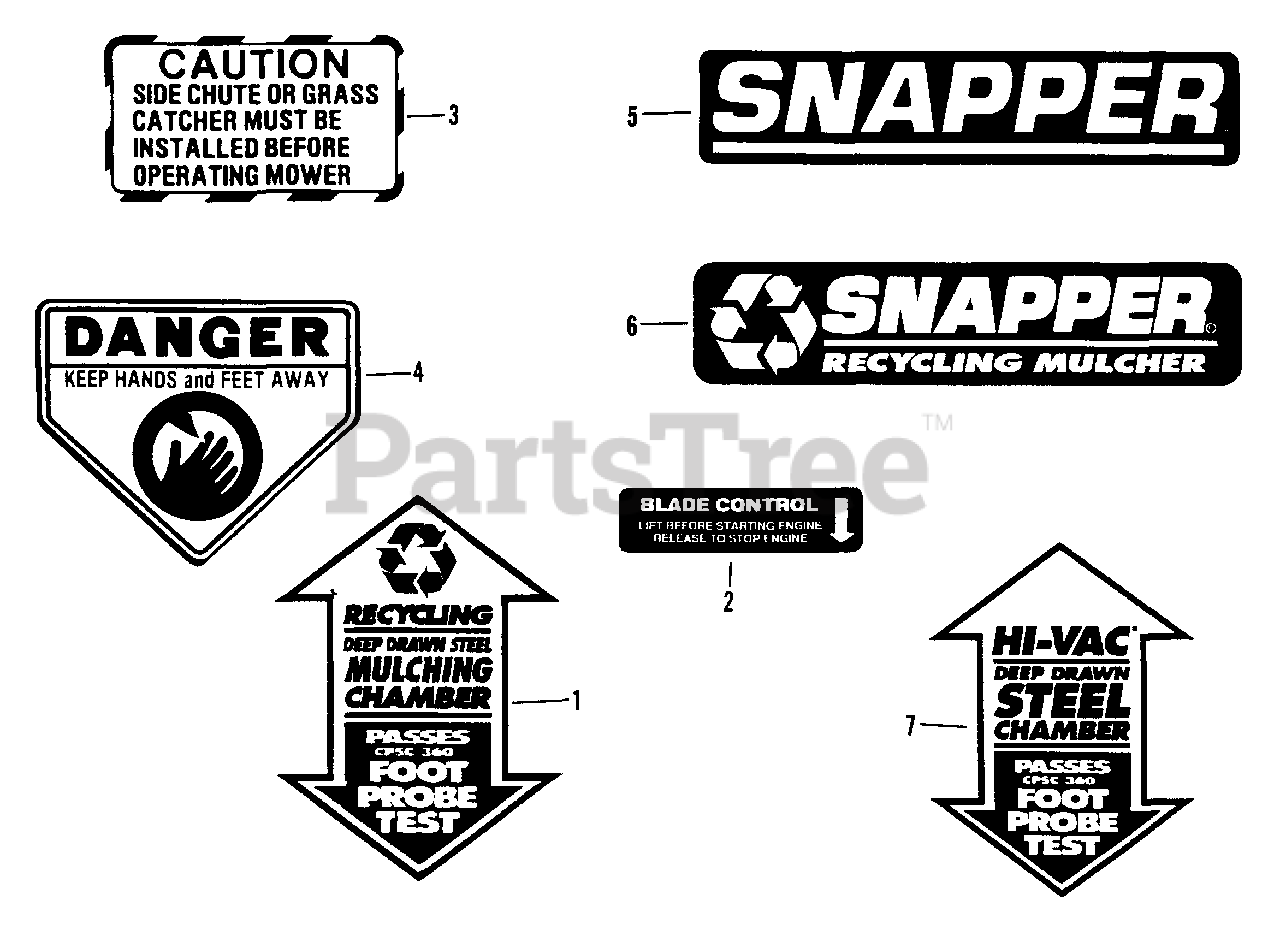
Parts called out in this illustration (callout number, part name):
1	DECAL, Mulching Chamber/Foot Probe
2	DECAL, Blade Control
3	DECAL, Caution
4	DECAL, Danger
5	DECAL, SNAPPER
6	DECAL, Hi-Vac/Foot Probe
7	DECAL, SNAPPER (Recycling)
